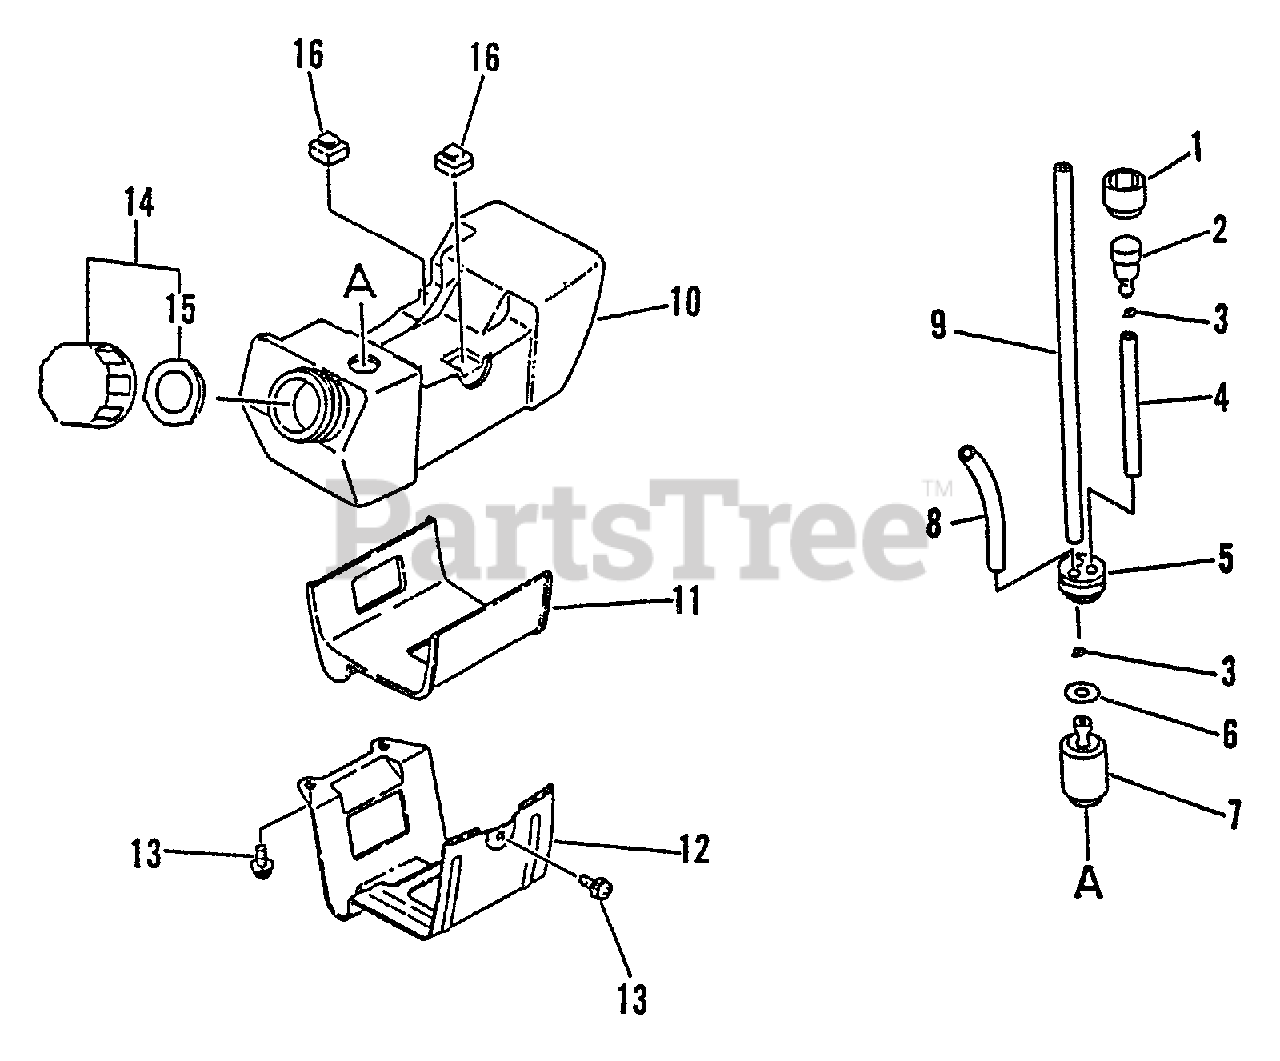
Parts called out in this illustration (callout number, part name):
1	HOLDER, VENT
2	VENT ASSY
4	PIPE, FUEL VENT 3×5×60
5	GROMMET, FUEL
6	WASHER 5.5×12×0.8
7	FILTER, FUEL
8	PIPE, FUEL RETURN 3×6×90 MM CLEAR
9	PIPE, FUEL 3x-5x-180
10	TANK, FUEL
11	CUSHION
12	GUARD, FUEL TANK
13	SCREW 5×10
14	CAP ASSY
15	GASKET, FUEL CAP
16	CUSHION
